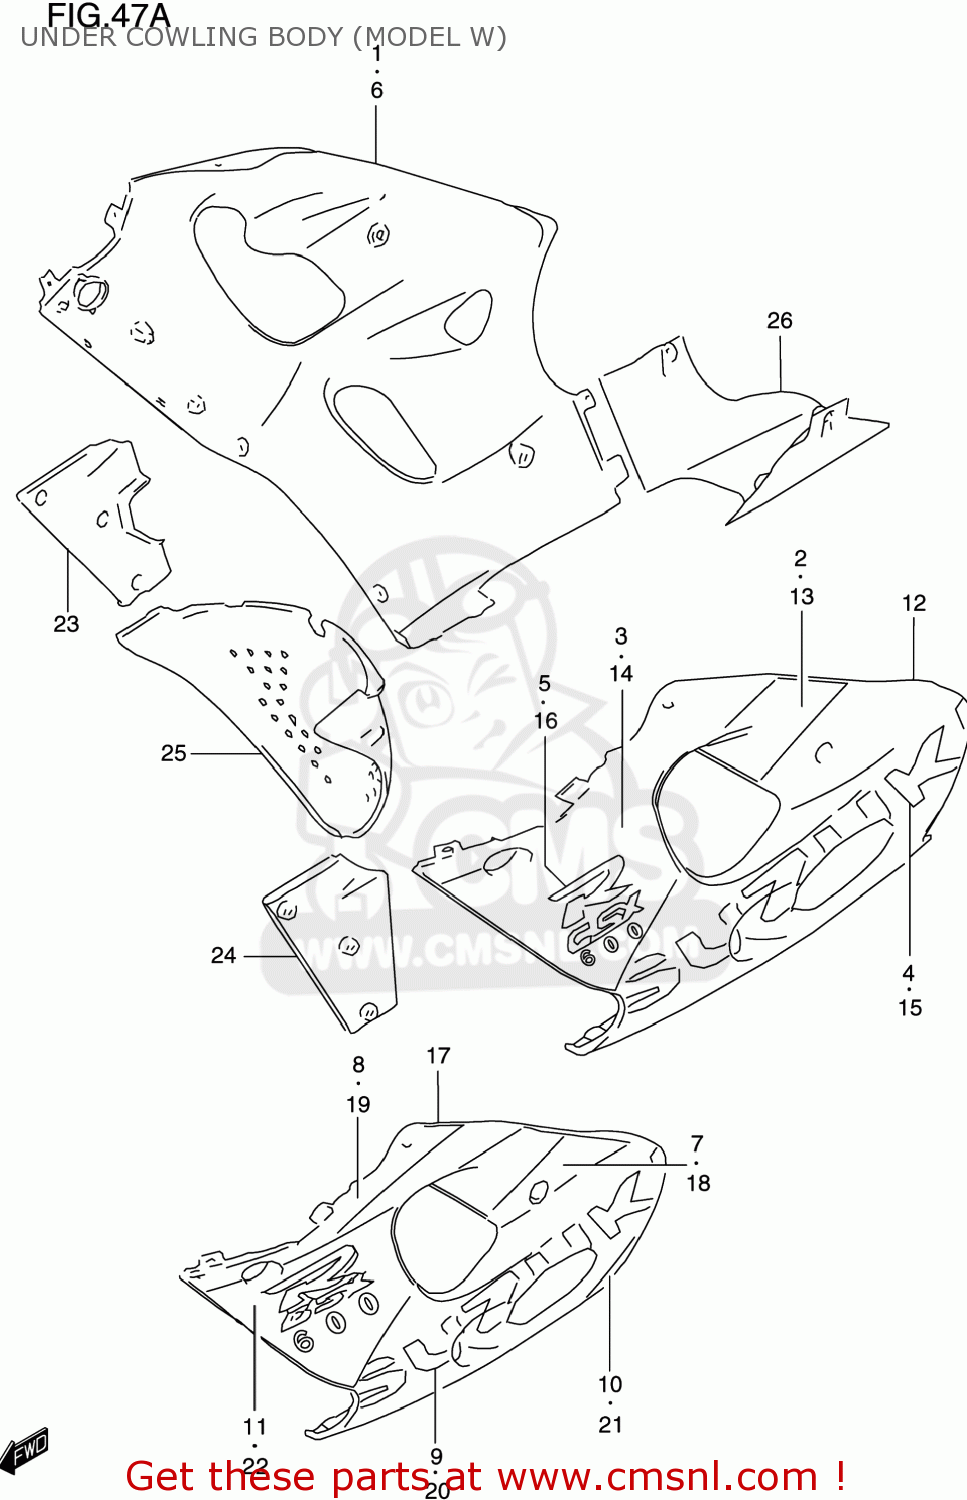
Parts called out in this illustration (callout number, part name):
1	COWLING ASSEMBLY,UNDER,RIGHT
2	TAPE SET,COWL UNDER,R
3	TAPE,COWL UNDER UPR,R
4	EMBLEM,COWLING UNDER,R
5	EMBLEM,COWLING UNDER,GSXR
6	COWLING ASSEMBLY,UNDER,RIGHT
7	TAPE SET,COWL UNDER,R
8	TAPE SET,COWL UNDER UPR,R
9	EMBLEM,COWLING UNDER,R
10	TAPE,COWL UNDER,R
11	TAPE,COWL UNDER,R
12	COWLING ASSEMBLY,UNDER,LEFT
13	TAPE,COWL UNDER,L
14	TAPE,COWL UNDER UPR,L
15	EMBLEM,COWLING UNDER,L
16	EMBLEM,COWLING UNDER,GSXR
17	COWLING ASSEMBLY,UNDER,LEFT
18	TAPE,COWL UNDER,L
19	TAPE SET,COWL UNDER,R
20	EMBLEM,COWLING UNDER,L (WHITE)
21	TAPE,COWL UNDER,R
22	TAPE,COWL UNDER,L
23	COWLING,UNDER INNER,R
24	COWLING,UNDER INNER,L
25	COWLING,UNDER CTR
26	COWLING ASSEMBLY,UNDER,REAR
